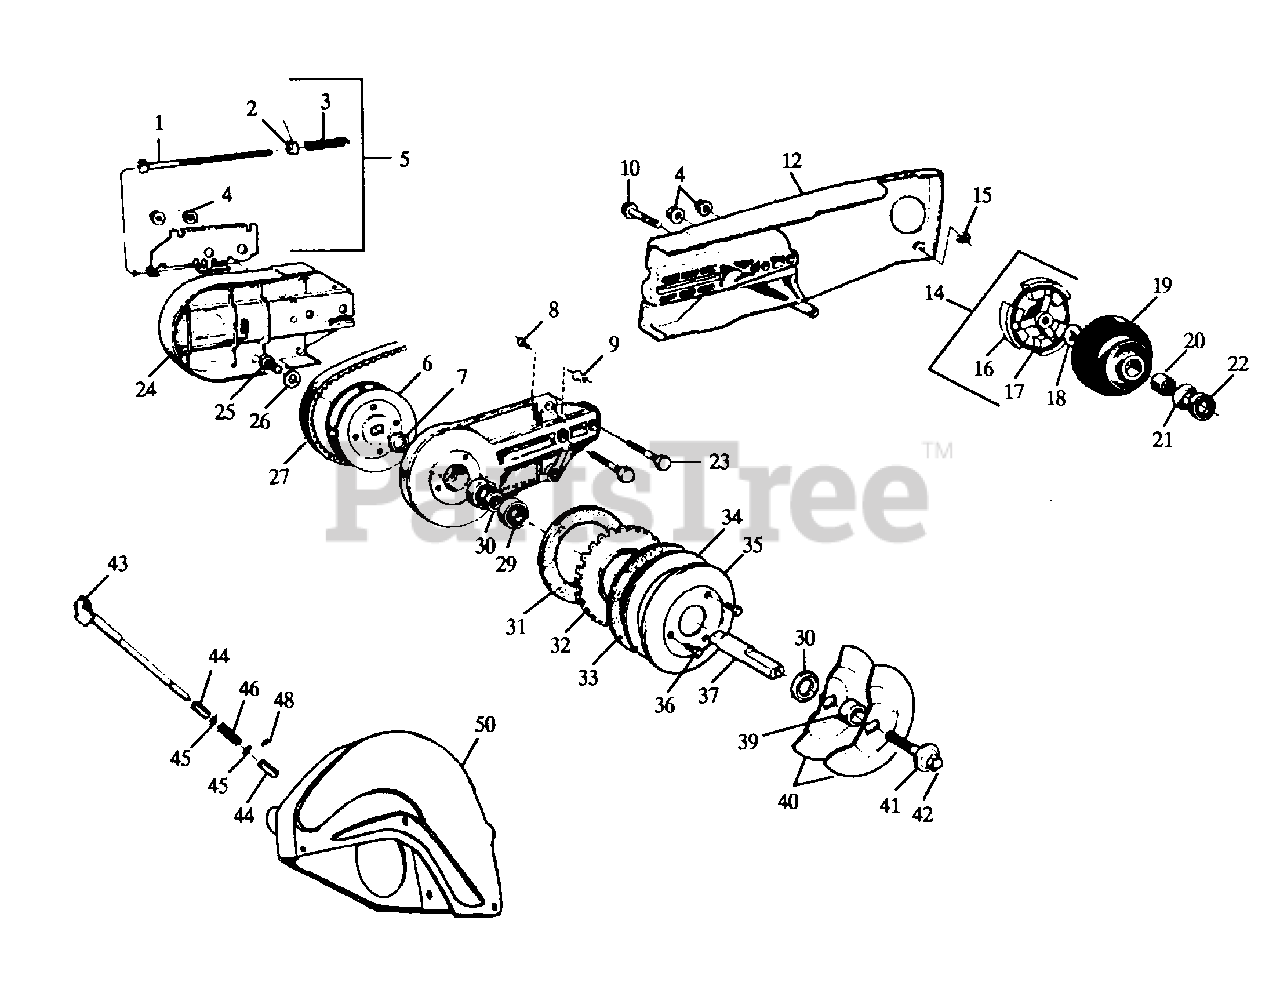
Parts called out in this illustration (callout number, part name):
3	Spring
5	Adjuster
6	Front Pulley
12	Cutting Arm
14	Clutch Ass'y.
15	Rubber Plug
19	Drive Wheel Ass'y.
20	Needle Bearing
22	Seal Ring
23	Bolt
24	Belt Guard
25	Screw
26	Washer
29	Ball Bearing
36	Screw
39	7/8"
39	20mm
39	1"
39	30.5mm
41	Washer
42	Bolt
